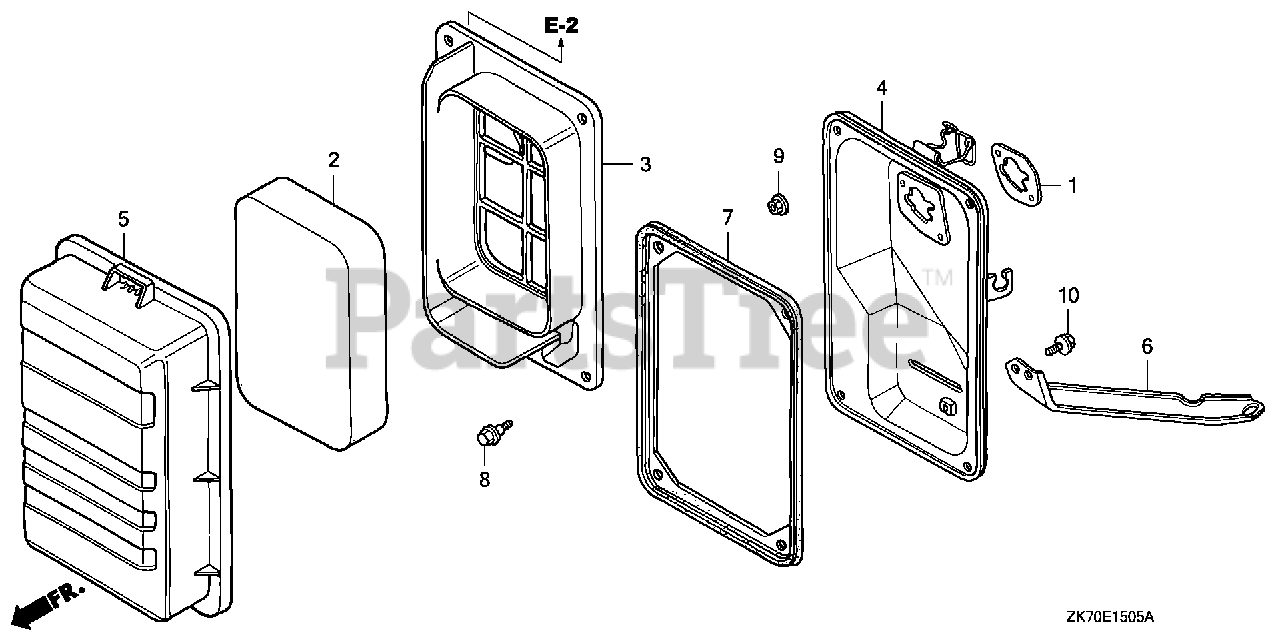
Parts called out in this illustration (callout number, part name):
1	GASKET, AIR CLEANER
2	ELEMENT, AIR CLEANER
3	SEPARATOR, AIR CLEANER
4	HOUSING, AIR CLEANER
5	COVER, AIR CLEANER
6	STAY, AIR CLEANER
7	SEAL, AIR CLEANER
8	BOLT, TURN SIGNAL SETTING
9	NUT, FLANGE (6MM)
10	BOLT, FLANGE (6X10)
